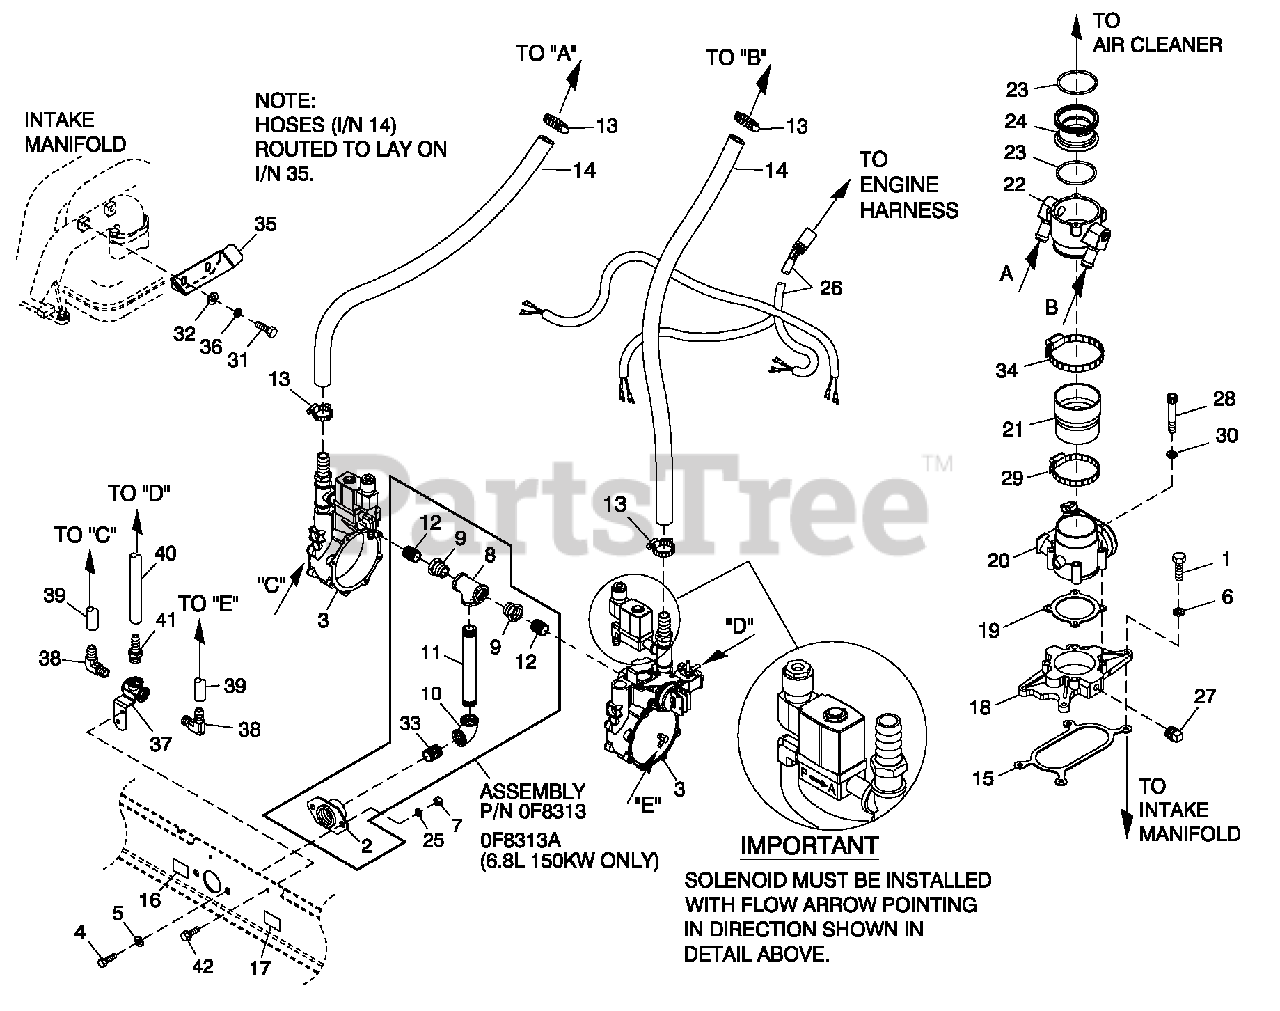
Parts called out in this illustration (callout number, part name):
1	SCREW HHC 5/16-18 X 1-1/4 G5
2	SUPPORT NAT GAS SOLENOID
3	REG 6.8L 100 KW LP CPL EMISS
4	SCREW HHC M12-1.75 X 20 G8.8
5	WASHER FLAT 1/2 ZINC
6	WASHER LOCK M8-5/16
7	NUT HEX M12-1.75 G8 YEL CHR
8	PIPE TEE 1-1/4 NPT
9	BSHG RDCRHEX1-1/4-3/4
10	ELBOW 90D1-1/4 NPT
11	NIPPLE PIPE 1-1/4 NPT X 3 (100KW & 130 KW)
12	NIPPLE CLOSE 3/4X1.375
13	CLAMP HOSE #10 .56-1.06
14	HOSE 3/4 ID SAE-30R2 (45" LG)
15	GASKET ADAPTER THROT BODY
16	DECAL INLET PRESSURE
17	DECAL FUEL INLET LPG
18	ADAPTOR THROTTLE BODY
19	GASKET GOVERNOR ACTUATOR
20	ACTUATOR BOSCH 60 GOVERNOR
21	REDUCER 3.0" TO 2.75" TURBO
22	MIXER 40/60MM ACTUATOR ASSY
23	O-RING 2-3/4X3/32X2-15/16
24	VENTURI THROTTLE 42MM (6.8L 100 KW)
25	WASHER LOCK 1/2
26	HARNESS, FUEL JUMPER DUAL REG
27	PLUG STD PIPE 1/4 STEEL SQ HD
28	SCREW SHC M6-1.0 X 50 C8.8
29	CLAMP HOSE #44 2.31-3.25
30	WASHER LOCK M6-1/4
31	SCREW HHC M6-1.0X 20 G8.8
32	WASHER FLAT M6
33	NIPPLE CLOSE 1.25 NPT X 1.625
34	CLAMP HOSE #52 2.81-3.75
35	BRACKET, HOSE RISER
36	WASHER LOCK M6-1/4
37	PIPE TEE W/ BRAC KET WELDED
38	BARBED EL 90 3/16X1/8
39	HOSE VACUUM 5/32 (12.0"LG)
40	HOSE VACUUM 5/32 (10.5"LG)
41	BARBED STR 1/8NPTX 3/16
42	SCREW THF M6-1 X 16 N WA Z/JS
